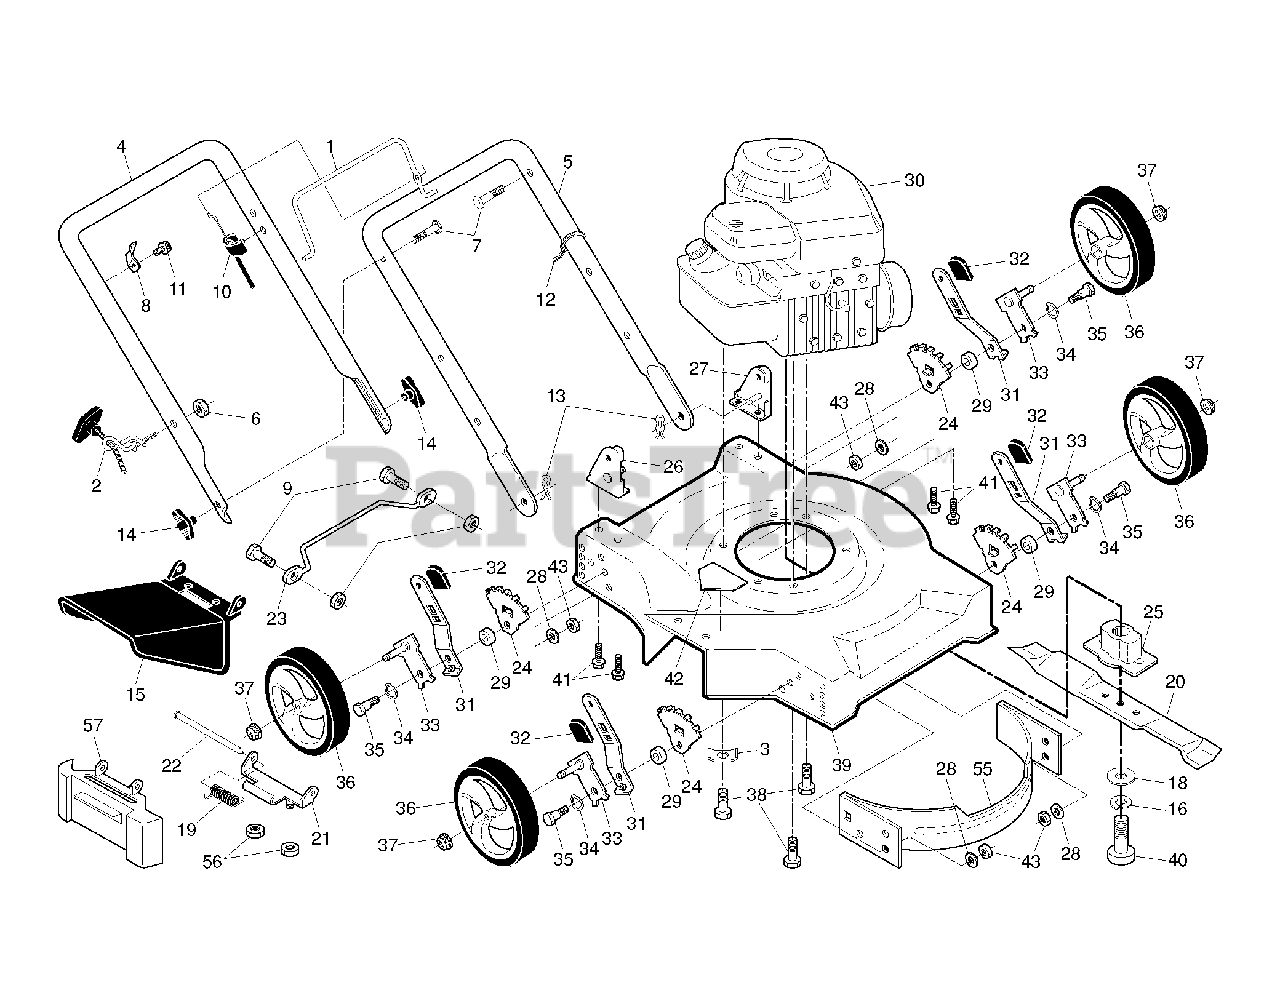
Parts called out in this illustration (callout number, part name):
1	BAIL.CONT.D.STRAIGHT.PUSH.BLK
2	GUIDE.ROPE.STD.BLK.ZIN
4	HANDLE.UPPER.FGD/PUSH.BLACK
6	NUT
7	BOLT, HANDLE 5/16-18X1.75
8	BRACKET.UPSTOP.RT
10	ENG ZONE CNTRL CB
12	TIE GUIDE
13	HAIRPIN COTTER
14	KNOB, DEFLECTOR
16	LOCKWASHER
18	WASHER,HARDEN
20	BLADE.20.MULCH.(50DK,6020MD)
21	HINGE DEFLECTOR
22	HINGE ROD
24	WHEEL ADJ BRACKET FRONT
25	BLADE ADAPTOR
26	HANDLE BRACKET ASM. RH
27	HANDLE BRACKET ASM. LH
28	WASHER
29	SPACER.HEIGHT.ADJUSTER
31	SELECTOR SPRING, FRONT
33	AXLE ARM ASSY.
34	WASHER FLAT
35	SHOULDER BOLT 5/16-18
37	NUT.HEX.FLANGE.3/8-16.LOCKNUT
38	BOLT 3/8-16X1-1/8
40	SCREW, HEX HD 3/8-24 X 1-3/8
41	SCREW 5/16-18
42	DECAL.INTERNATIONL.CUTFINGER
43	NUT.CENTERLOCK.5/16-
56	LOCKNUT
